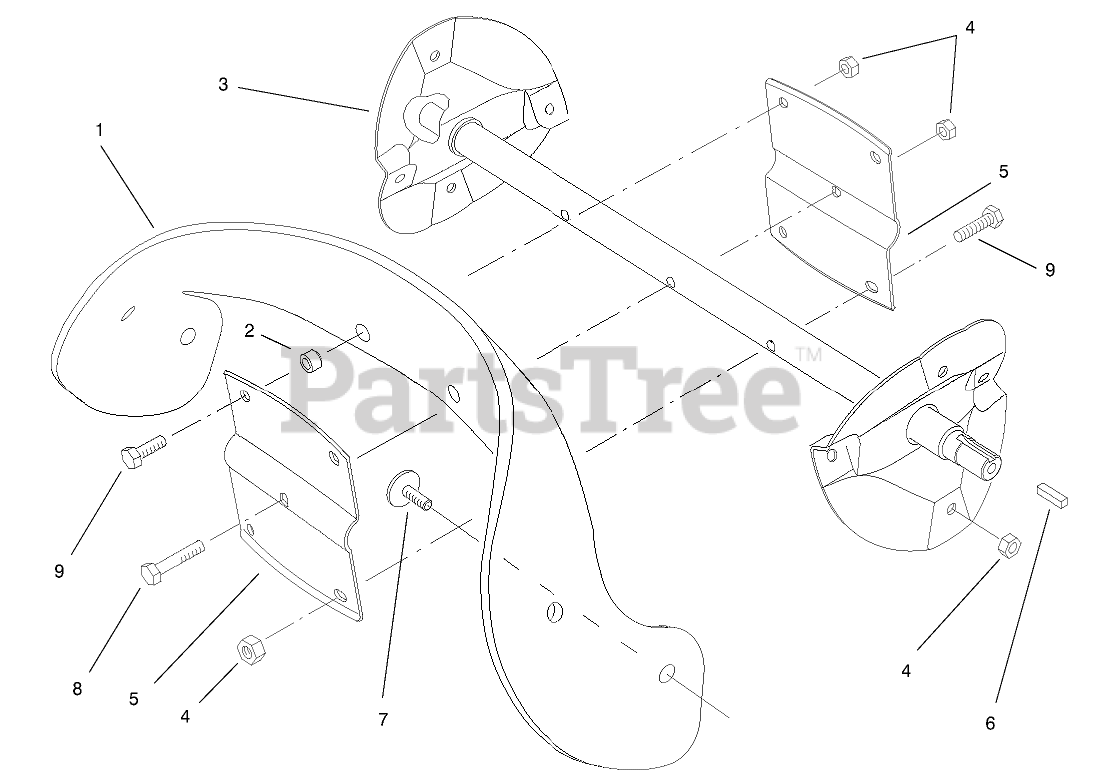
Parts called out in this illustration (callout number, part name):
1	BLADE-ROTOR
2	SPACER-BLADE, ROTOR
3	ROTOR ASM
4	NUT-LOCK, NI
5	HALF-ROTOR
6	KEY-SQUARE
7	SCREW
8	SCREW-HH
9	SCREW-HH
